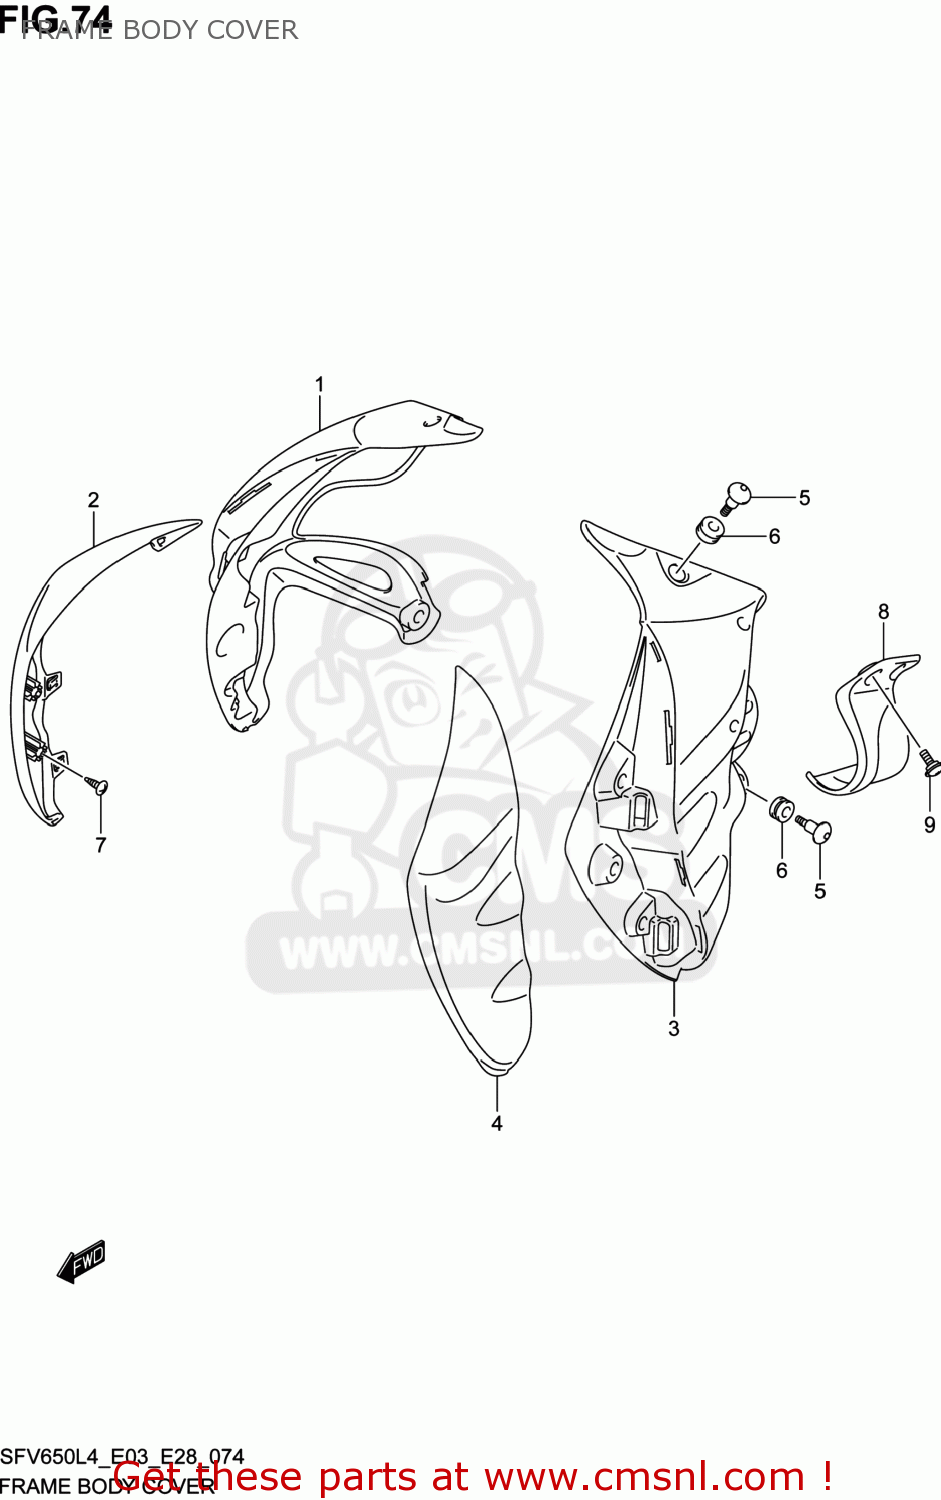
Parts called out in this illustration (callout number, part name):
1	COVER,FRAME BODY,R
2	COVER,FRAME BODY,R
3	COVER,FRAME BODY,L
4	COVER,FRAME BODY,L
5	SCREW(6X20)
6	CUSHION
7	SCREW
8	COVER,FRAME BODY RR,L
9	SCREW(5X13)
